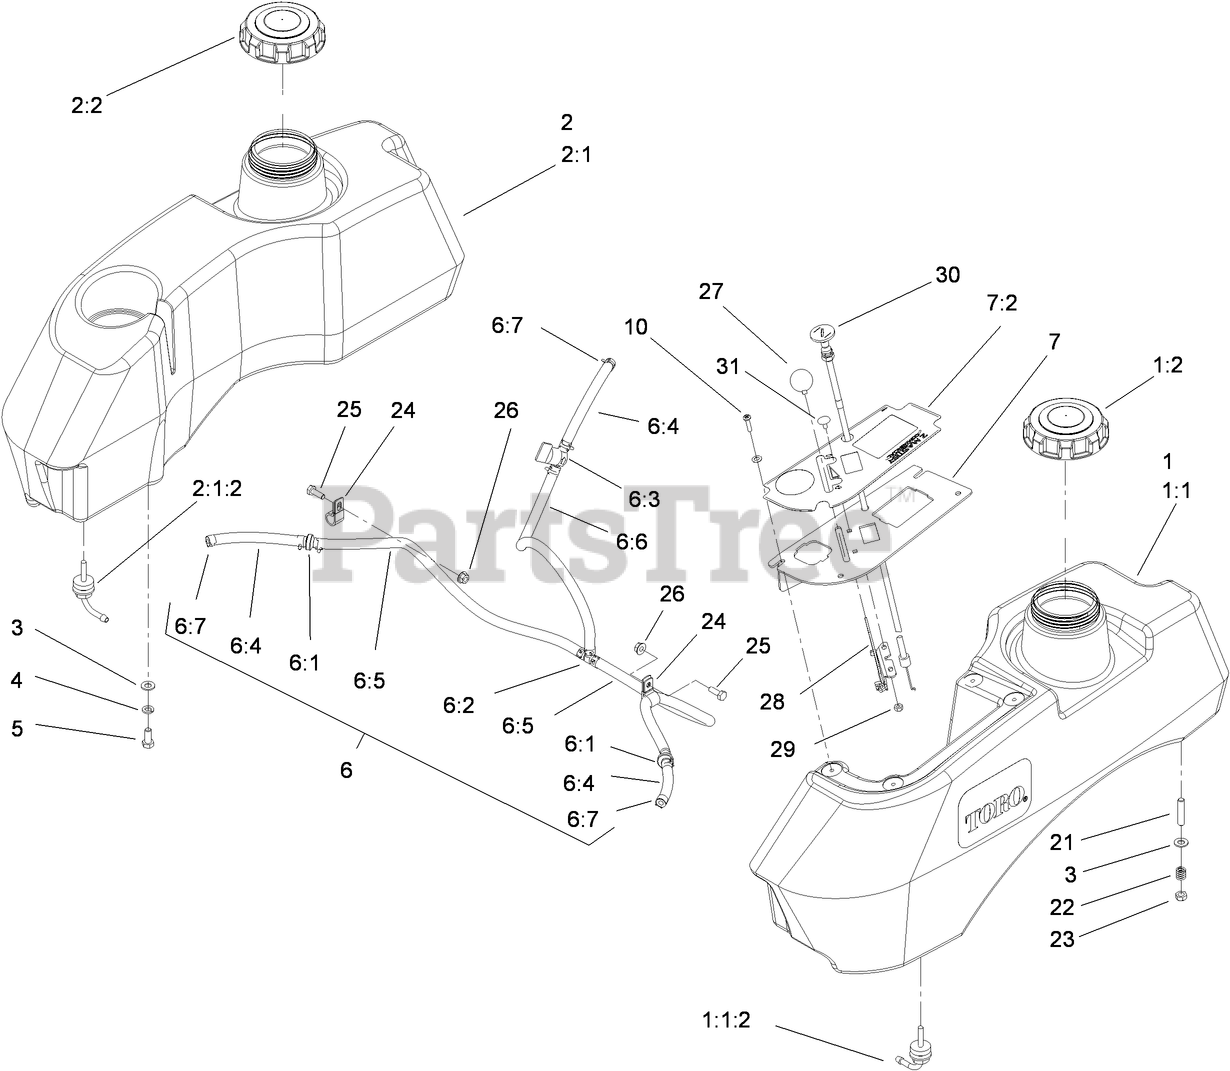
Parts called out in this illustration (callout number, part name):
1	LH FUEL TANK SERVICE KIT
1:1	LH FUEL TANK ASM
1:1:2	FITTING-FUEL, BULKHEAD
1:2	CAP-FUEL, GAS
2	RH FUEL TANK SERVICE KIT
2:1	RH FUEL TANK ASM
2:1:2	FITTING-FUEL, BULKHEAD
2:2	CAP-FUEL, GAS
3	WASHER-PLAIN
4	WASHER-LOCK
5	SCREW-HH
6	Hose-Fuel
6:1	VALVE-CHECK, FUEL
6:2	FITTING-TEE, BARBED
6:3	VALVE-FUEL
6:4	HOSE-FUEL
6:5	HOSE-FUEL
6:6	HOSE-FUEL
6:7	Clamp-Hose
7	CONTROL PANEL ASM
7:2	DECAL-PANEL, CONTROL
10	SCREW-PPH
22	SPRING-TANK, FUEL
23	NUT-LOCK, NI
24	CLIP-LOOM
25	SCREW-HH
26	NUT-HF
27	KNOB-BALL
28	THROTTLE CABLE ASM
29	NUT-LOCK, NI
30	CONTROL-CHOKE, PUSH / PULL
31	BOLT-CARR
